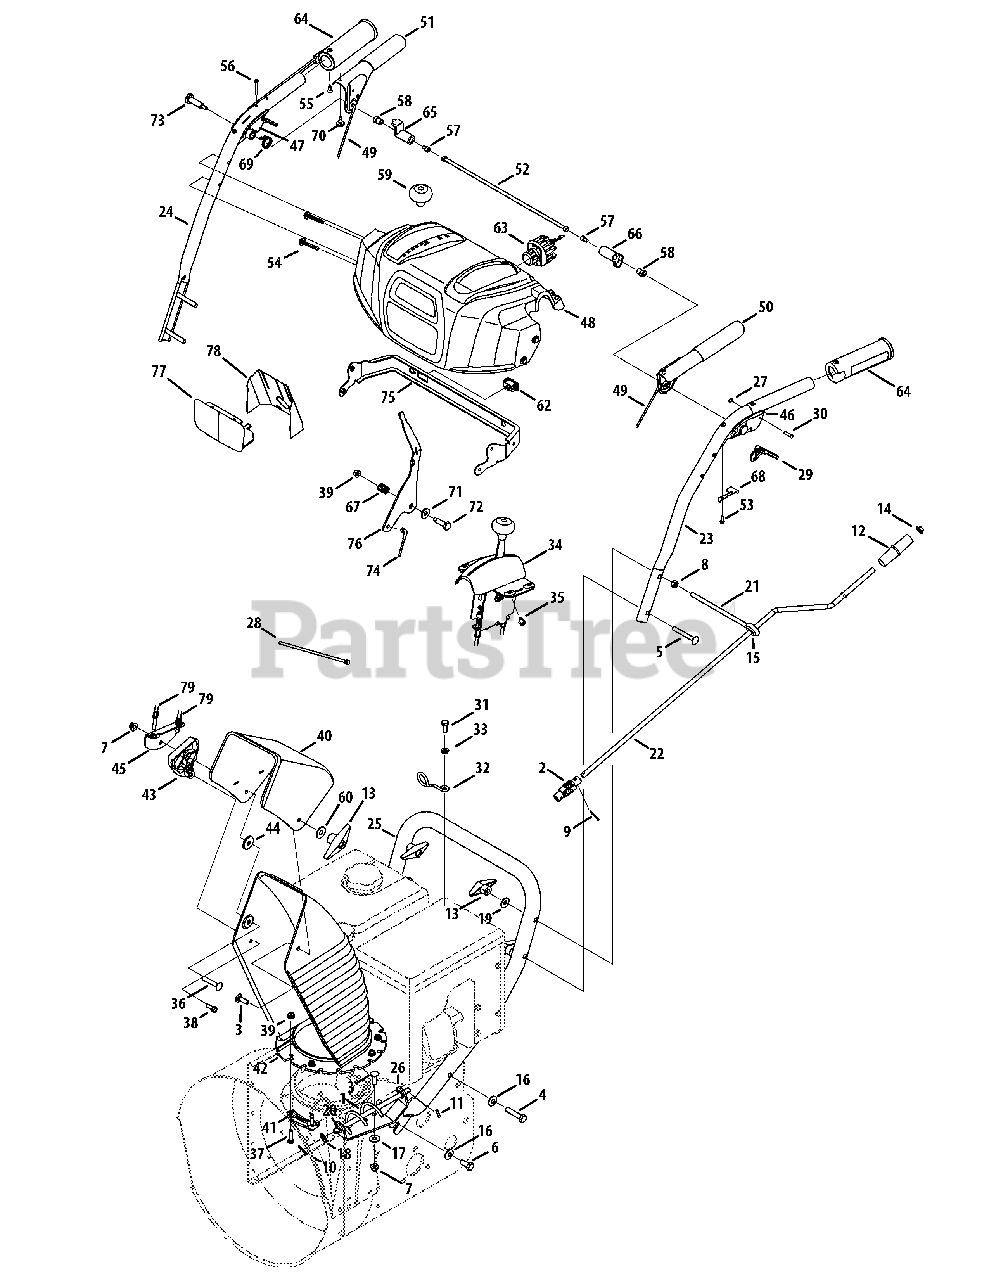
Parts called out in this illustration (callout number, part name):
1	Chute Crank Assembly
2	Joint Block Assembly
3	Screw, Carriage, 5/16-18 x 1.0
4	Screw, Hex, 3/8-16 x 2.00 Lock, Gr5
5	Screw, Carriage, 5/16-18 x 2.5
6	Screw, Hex, 3/8-16 x 1.0 Lock, Gr5
7	Flange Lock Nut, 5/16-18
8	Hex Nut, 5/16-18
9	Internal Cotter Pin
10	Internal Cotter Pin
11	Spring Pin
12	Knob, Crank
13	Knob, Wing Nut, 5/16-18
14	Cap, Push, 3/8
15	Grommet, Rubber
16	Washer, Bel, .375 x .87 x .063
17	Washer, Flat, .349 x .879 .063
18	Washer, .375 x .738 x .063
19	Washer, Belleville, .34 x .872 x .06
20	Plastic Bushing, .380 I.D.
21	Eye Bolt
23	Handle, Upper - LH
24	Handle, Upper - RH
25	Handle, Lower
26	Chute Crank Bracket
27	Ring, Retainer
28	Cable Tie
29	Trigger
30	Pin, 3/16
31	Hex Head Screw, MB 1.25
32	Cable Guide
33	Flat Washer, .330 x .630 x .0635
34	2-Way Chute Control™ Assy
35	Hi-Lo Screw, 1/4-15 x 0.5
36	Bolt, Carriage, 5/16-18 x 1.75
37	Screw, 1/4-20 x 1.00
38	Hi-Lo Screw, 1/4-15 x .75
39	Flange Lock Nut, 1/4-20
40	Upper Chute
41	Chute, Flange Keeper
42	Lower Chute
43	Chute Tilt Cable Guide
44	Flat Washer
45	Cable Bracket
46	Handle Clutch Lock - LH
47	Handle Clutch Lock - RH
48	Handle Panel
49	Cable Assembly, Auger/Drive
49	Cable, Clutch
49	Spring, Extension
50	Handle Engage Assy - LH
51	Handle Engage Assy - RH
52	Rod Ass’y, Clutch Lock Pivot
53	Screw, #8-16 x 0.50
54	Screw, 1/4-20 x 1.625
55	AB Screw, #10-16
56	Screw, #10-24 x 0.375
57	Screw, 1/4-20 x.375
58	Shoulder Nut, 1/4-20
59	Shift Knob
60	Flat Washer, .349 x .879 x .063
62	Htd. Hand Grip on/off Switch
63	Light Socket
64	Heated Hand Grip
65	Lock Plate
66	Clutch Lock Cam
67	Compression Spring
68	Clutch Lock Spring
69	Torsion Spring
70	Rubber Bumper
71	Flat Washer, .385 x .87 x .06
72	Shoulder Screw
73	Shoulder Screw, 1/4-20 x 1.345
74	Speed Selector Cable
75	Panel Bracket
76	Shift Lever
77	Lens Panel
78	Reflector Label
79	Cable, Chute Tilt
